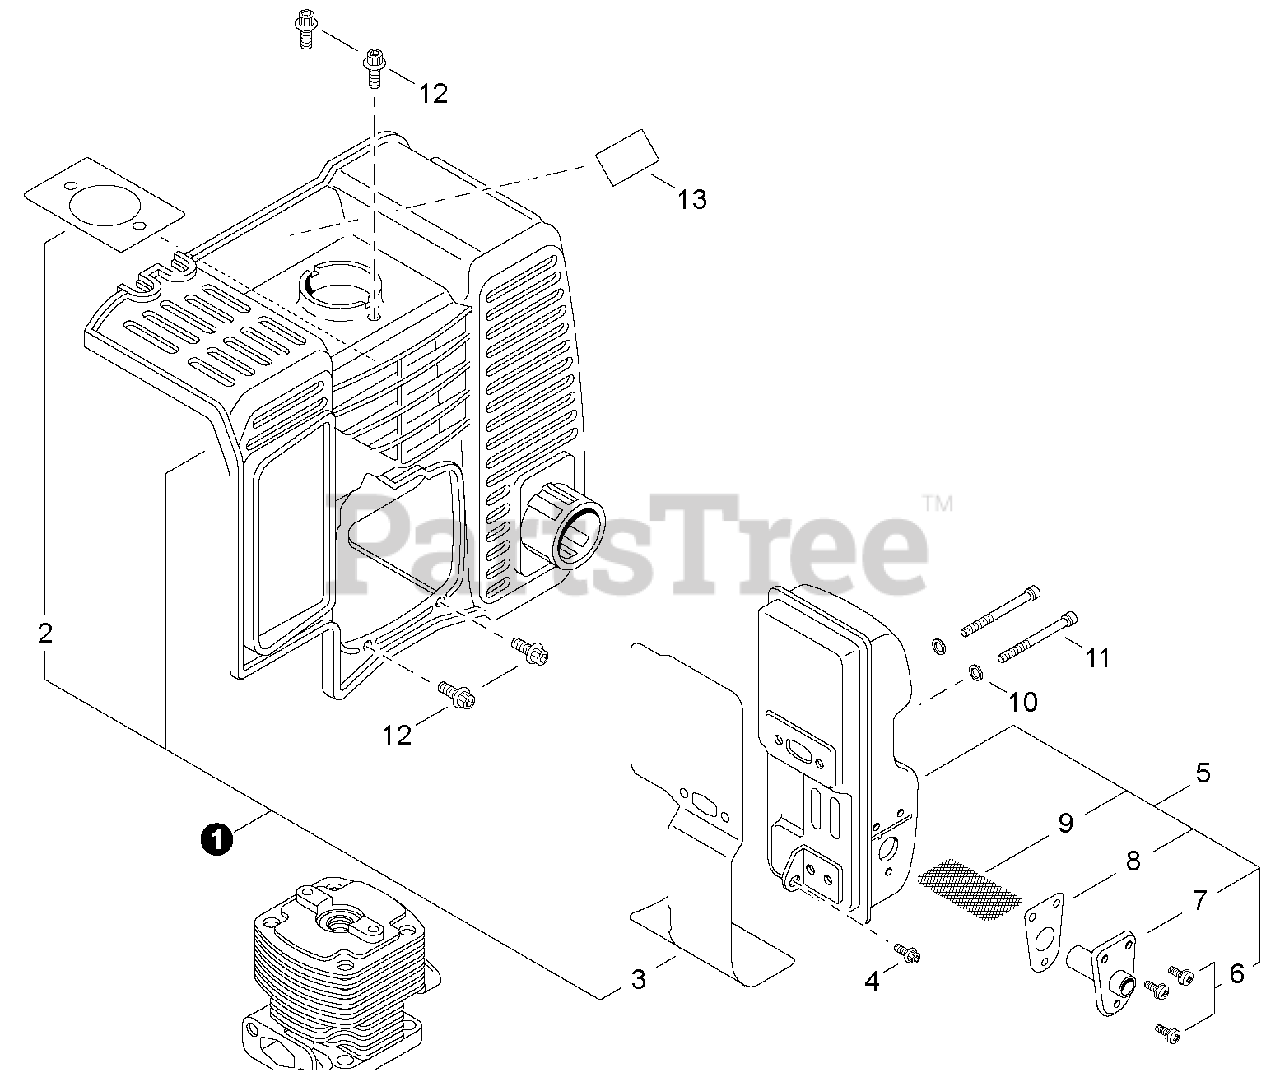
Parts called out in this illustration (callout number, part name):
1	COVER ASSY, ENGINE
2	SHIELD, HEAT
3	HEAT SHIELD, EXHAUST
4	BOLT M5×12
5	MUFFLER ASSY
6	SCREW M4×12
7	GUIDE, EXHAUST
8	GASKET, EXHAUST
9	SCREEN, SPARK ARRESTER
10	WASHER 6.5×11.5×0.8
11	BOLT
12	BOLT, ADHESIVE M5×16
13	LABEL, CAUTION
